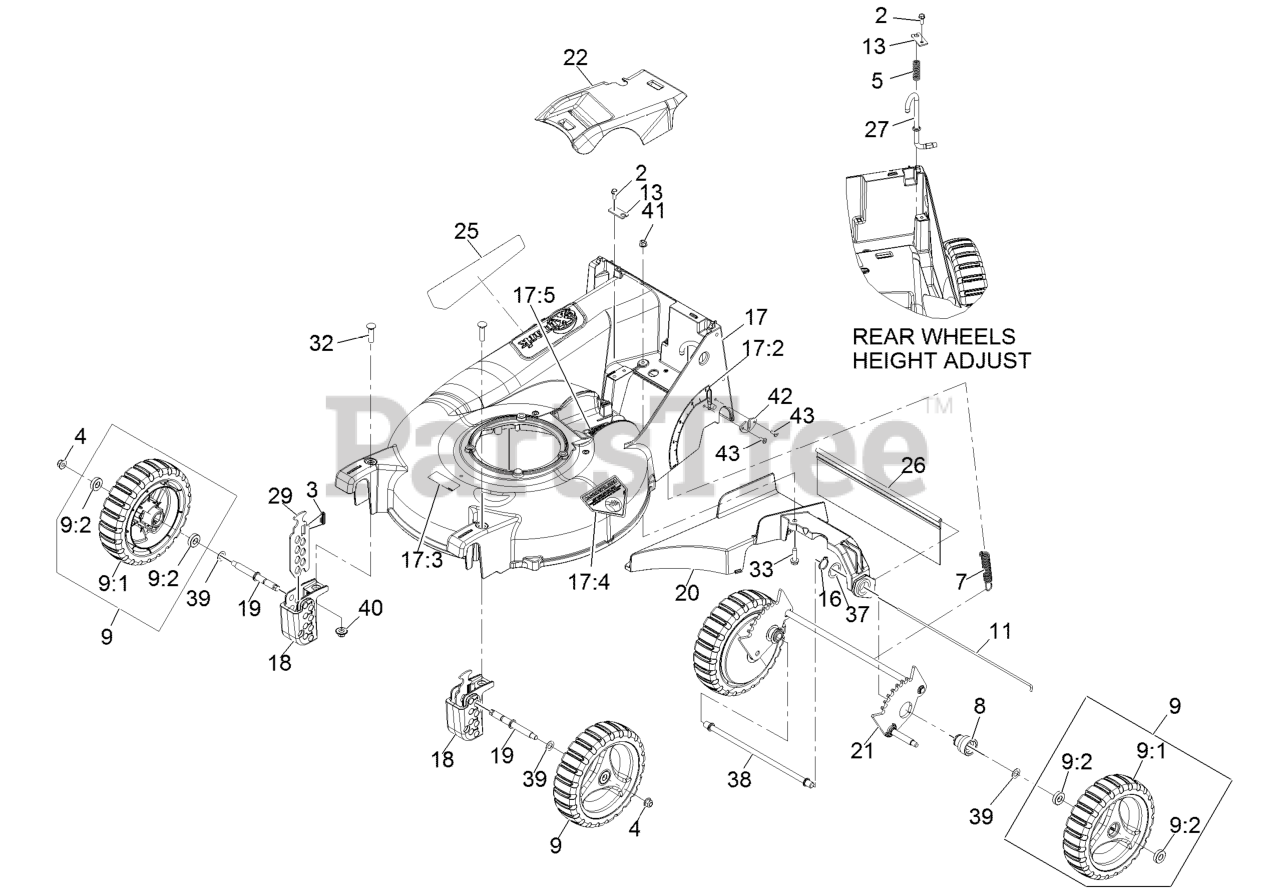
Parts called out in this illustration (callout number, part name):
2	SCREW-HWH
3	SPRING-COMPRESSION
4	NUT-HF, NI
5	SPRING-COMPRESSION
7	SPRING-EXTENSION
8	HOUSING-BEARING
9:2	BEARING-BALL
11	ROD,SHIELD
13	BRACKET,MOUNT
16	RING-RETAINING
17	DECK W/DECALS
17:2	DECAL-HEIGHT OF CUT
17:3	DECAL-BLADE
17:4	DECAL-DANGER
17:5	DECAL-COVER MISSING
18	BLOCK,FRONT QUADRANT
19	AXLE-WHEEL
21	WLD,REAR AXLE P21
22	COVER,BELT
25	DECAL-COMM 21 S-SERIES
26	SHIELD-TRAILING P21
27	ROD-HEIGHT ADJ P21
29	PLATE, FRONT HEIGHT
32	SCREW-CARR
33	SCREW-HWHTF
38	SPACER-HOUSING
39	WASHER-PLAIN
40	Nut-Nyloc 3/8-16 Flg
41	NUT-HF, NI
42	PLATE,WEAR
43	RIVET-BLIND
